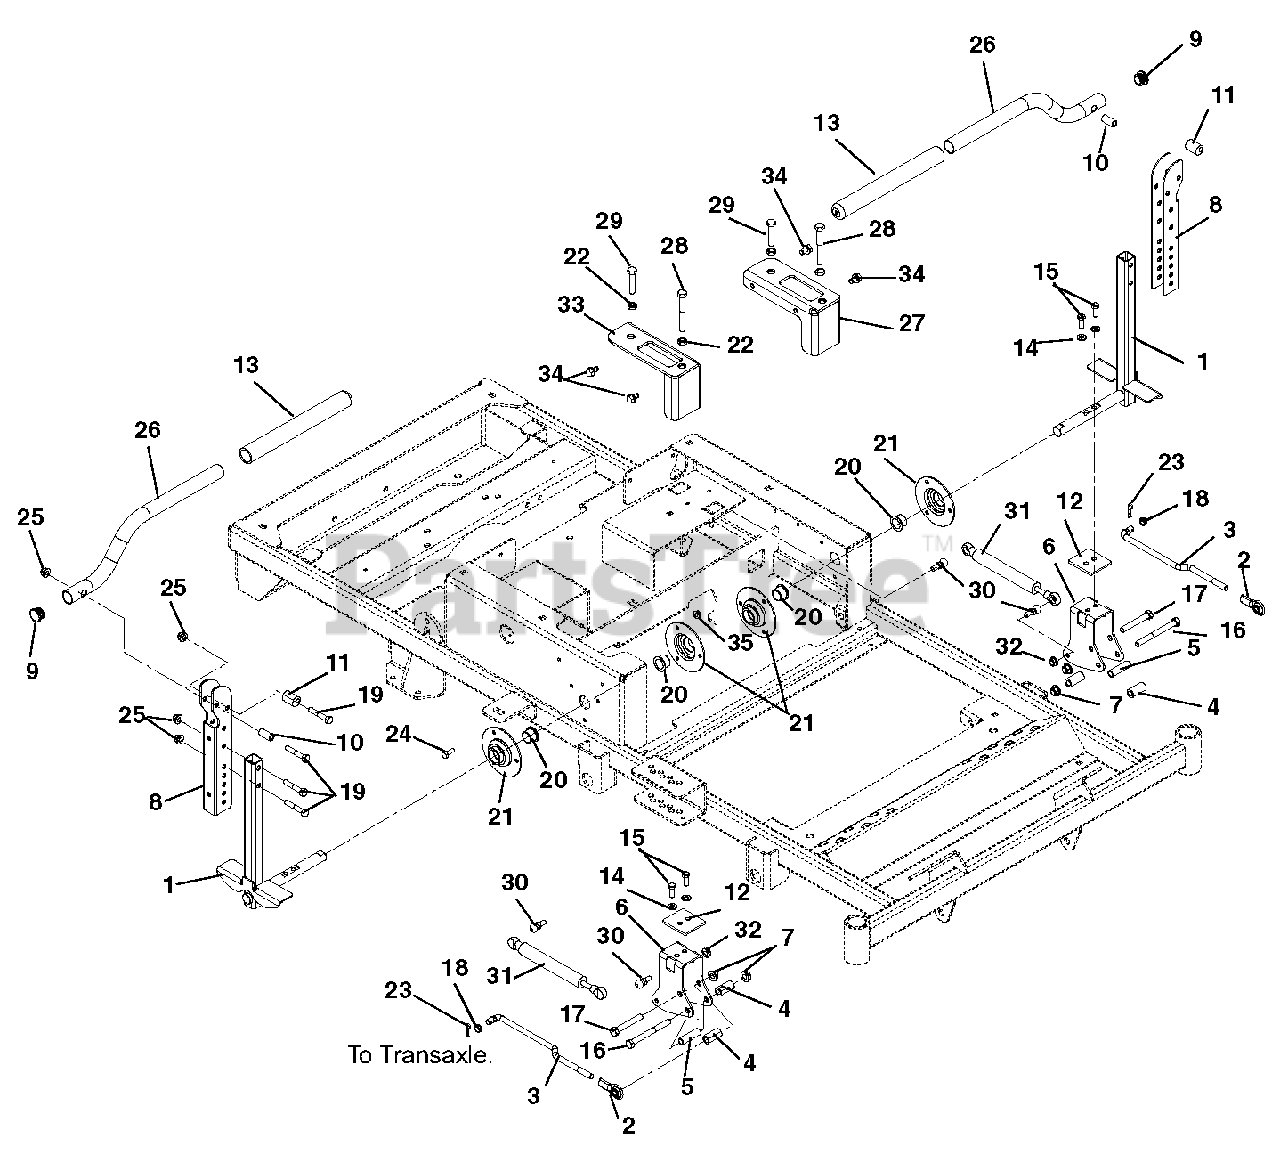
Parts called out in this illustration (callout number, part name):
1	Weldment, Control Link
2	Rod End, .38 Right Hand
3	Link, Transmission
4	Bushing, Spacer .390 x .625 x 1.25 Promaster
5	Spacer, Steering
6	Bracket, Steering
7	Nut, .38-16 Nyloc Flange
8	Channel, Upper Handlebar
9	Caplug, Handlebar
11	Eccentric
12	Plate, Steering Reinforcing
13	Grip, Handle
14	Washer, Locking .31 x .078
15	Bolt, Hex .31-18 x 1.00 Grade 8
16	Bolt, Hex .38-16 x 3.75 Grade 5
17	Bolt, Hex .38-16 x 2.50 Grade 5
18	Bushing, Polyliner 322-C
19	Bolt, Hex .31-18 x 1.75 Grade 5
20	Bushing, Flange .750 x 1.000 x .625 x 1.250
21	Bearing Flange
22	Nut, Hex Jam .375-16
23	Pin, Hair Internal .08 x .18 x 1.18
24	Bolt, Hex .25-20 x .75 Grade 5
25	Nut, .31-18 Nyloc Flange
26	Handlebar, ZTXL
27	Bracket, Left Hand Speed Control
28	Bolt, Hex .38-16 x 3.00 Grade 5
29	Bolt, Hex .375-16 x 1.750 Full Thread
30	Stud, Ball
31	Damper, ZT XL
32	Nut, Locking Top Flange .31-18
33	Bracket, Right Hand Speed Control
34	Screw, Tapping .31-18 x .50 Hex Washer Head
35	Nut, Locking Top Flange .25-20
